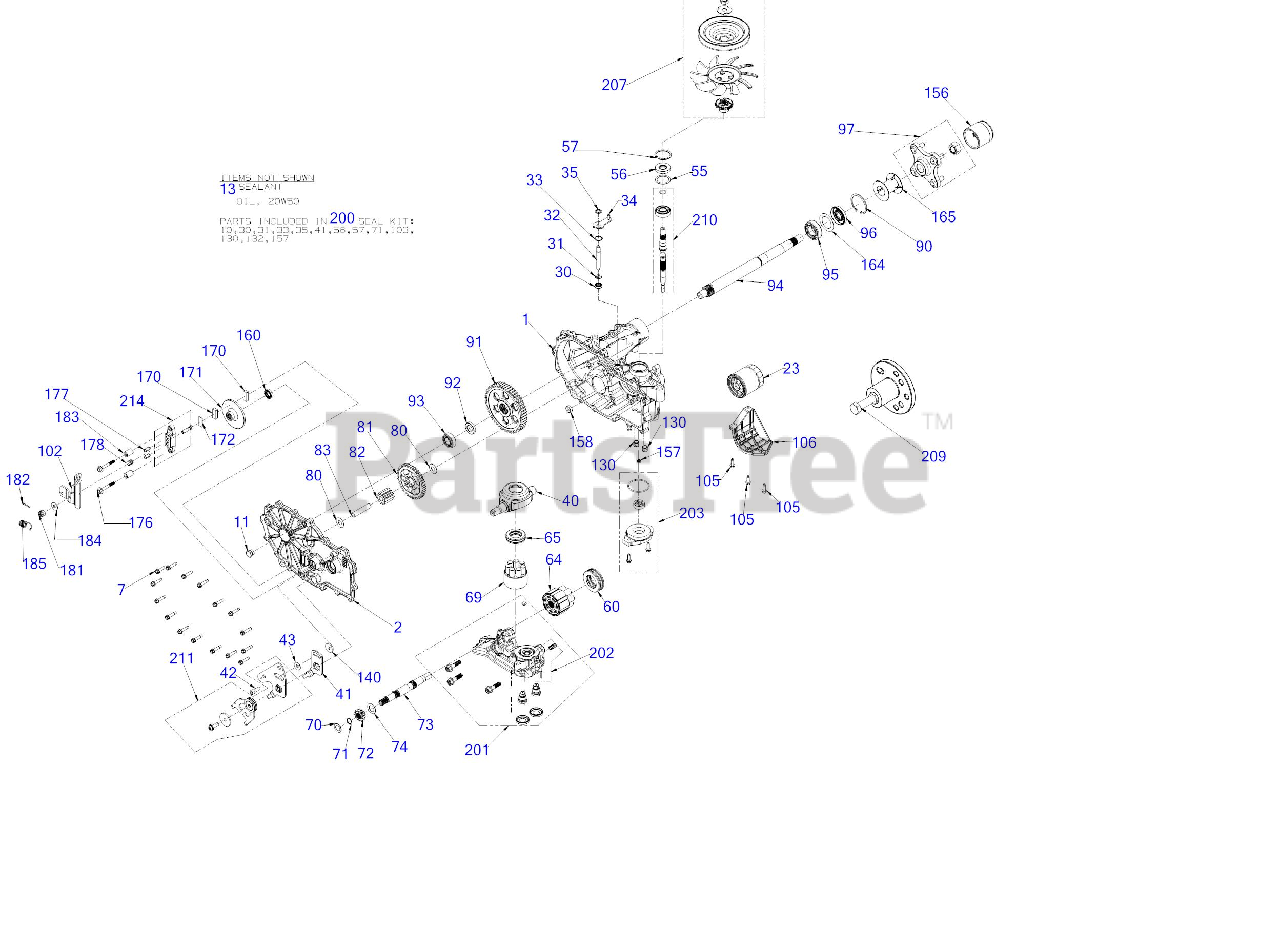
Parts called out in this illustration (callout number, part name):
1	HOUSING KIT (LH)
2	CONTROL COVER KIT (LH)
7	SCREW-WASHER HEAD
11	VENT PLUG
13	SEALANT-HOUSING
23	FILTER-OIL
30	SEAL-LIP .375
31	RETAINING RING
32	BYPASS RODS
33	RETAINING RING
34	ARM-BYPASS
35	RETAINING RING
40	SWASHPLATE-TRUNNION
41	ARM-NEUTRAL (LH)
42	SCREWS KIT-RTN
43	FLAT WASHER
55	WASHER 1.23X1.56X
57	RETAINING RING
60	THRUST BEARING
64	BLOCK ASSEMBLY-CYLINDER
65	THRUST BEARING
69	BLOCK KIT-CYLINDER
70	FLAT WASHER
71	RETAINING RING
72	GEAR - 13 TOOTH STEEL
73	MOTOR SHAFT
74	MOTOR SHAFT WASHER
81	GEAR - 46 TOOTH
82	GEAR-11 T
83	PIN-JACKSHAFT
90	RETAINING RING
91	GEAR - 54 TOOTH
92	SPACER .75X1.32X.257
93	BALL BEARING 3/4
94	AXLE SHAFT
95	BALL BEARING
97	HUB KIT-4 BOLT
102	ARM-BRAKE
106	GUARD-FILTER (LH)
130	TUBE-CHARGE TRIPLE O-RING
140	SPACER .32 x 1.005 x .179
157	KIT-GEROTOR SEAL
158	MAGNET-RING
165	TUBE-AXLE 2.03
170	BRAKE PUCK
171	ROTOR-BRAKE
172	PLATE-PUCK
176	BOLT-SPECIAL FLANG
177	ACTUATING PIN
178	BRAKE SPRING
181	NU-HEX INS JAM
182	COTTER PIN-3/32
183	SPACER-TORSION SPG
184	FLAT WASHER
185	BRAKE SPRING
200	KIT - SEAL
201	CENTER SECTION KIT (LH)
202	KIT-CHARGE RELIEF
203	CHARGE KIT
207	FAN & PULLEY KIT
209	PULLER KIT-HUB
210	INPUT SHAFT KIT
211	RETURN KIT-NEUTRAL
214	BRAKE YOKE ASSEMBLY
